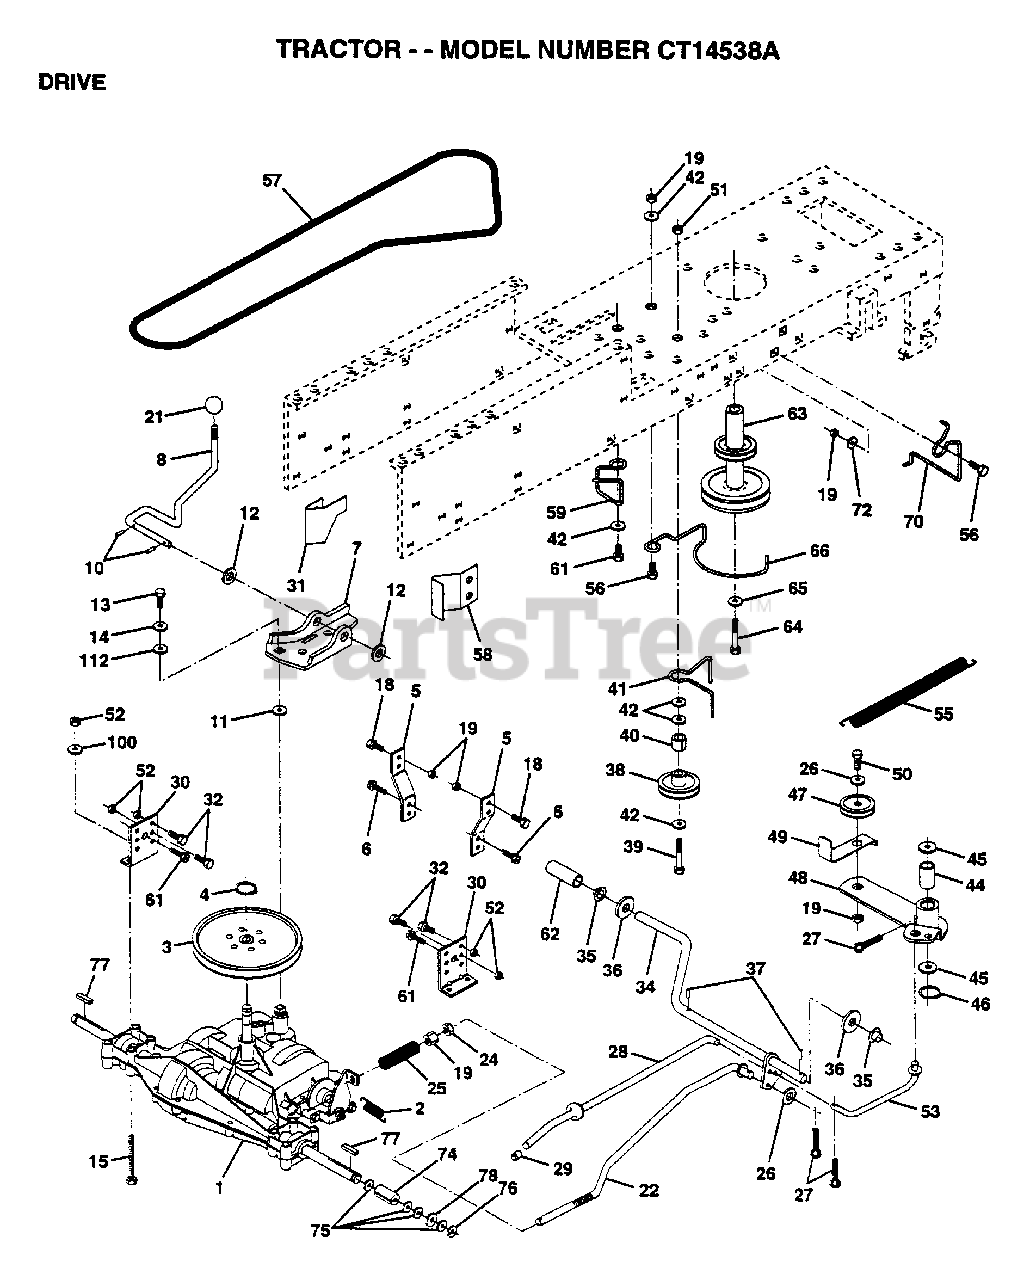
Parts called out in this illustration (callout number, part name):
2	SPRING.BRAKE.RETU
3	PULLEY TRANS
5	STRAP TORQUE
6	SCREW
8	SHIFT ROD
10	PIN COTTER 1/8
11	WASH-SHFT PLT LT
12	WASHER
13	BOLT.1/4-28.W/PAT
14	LOCKWASHER
15	BOLT HEX
18	BOLT
19	NUT
21	KNOB T (1/2-HOLE)
22	BRAKE ROD
24	NUT
25	SPRING ROD LT
26	WASHER
27	COTTER PIN
28	ROD.BRAKE.PARK.LT
29	PLUNGER CAP T
30	TRANSAXLE MTG BKT
31	"KEEPER,BELT LH T"
32	BOLT
35	NYLON BEARING
36	WASHER LT
38	PULLEY.IDLER.FLAT
39	BOLT
40	SPACER T
41	BELT KEEPER LT
42	WASHER
44	"LY, BEARING"
45	WASHER LT
46	KLIP RING
48	ARM IDLER
49	RETAIN BELT
53	"LINK, CLUTCH T"
55	"SPRING, RETURN LT"
58	"KEEPER,BELT RH T"
59	KEEPER BELT CNTSP
61	SCREW
62	PEDAL COVER T
63	PULLEY.ENGINE
64	BOLT
65	LOCKWASHER
66	KEEPER.BELT.ENG.L
70	KEEPER BELT ENG
72	WASHER
74	SPACER LT
75	WASHER
76	E-RING LT
77	SQUARE KEY
78	WASHER
100	WASHER M
112	WASHER LT
